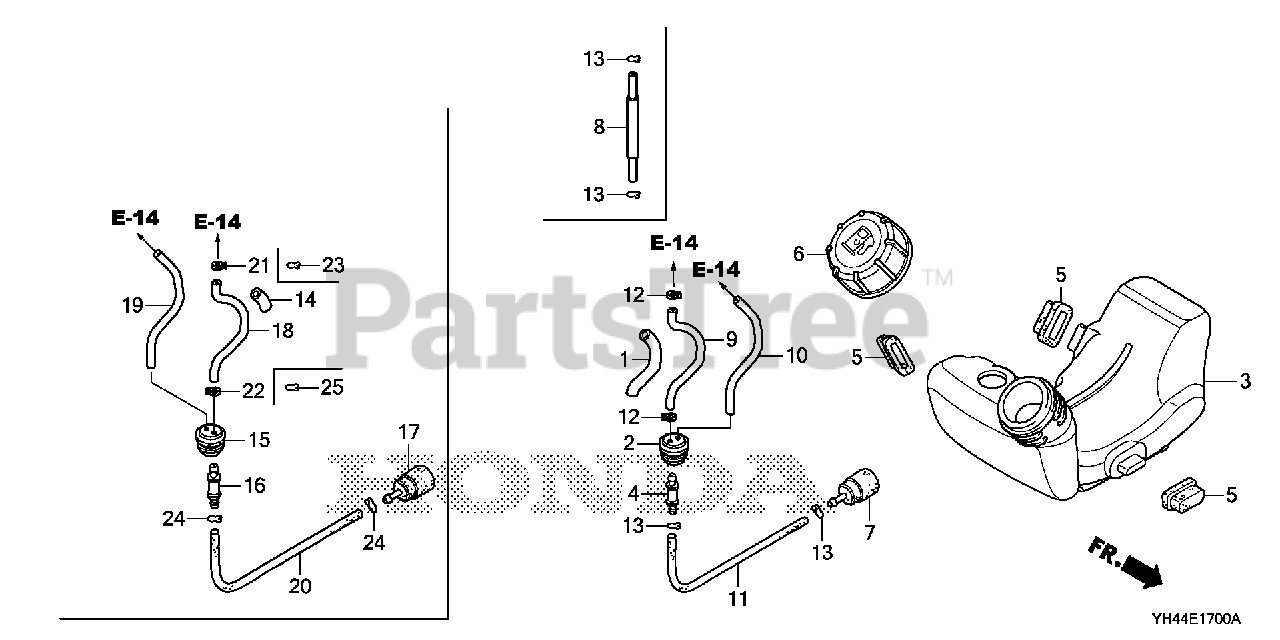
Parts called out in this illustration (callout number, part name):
1	PROTECTOR, TUBE
2	GROMMET, FUEL TUBE
3	TANK, FUEL
5	RUBBER, TANK MOUNTING
6	CAP ASSY., FUEL TANK
7	FILTER, FUEL
9	TUBE, FUEL
10	TUBE, FUEL RETURN
11	TUBE A, FUEL
12	CLAMP, TUBE
13	CLIP, TUBE
14	PROTECTOR, TUBE
15	GROMMET, FUEL TUBE
16	JOINT, FUEL TANK
17	FILTER, FUEL
18	TUBE, FUEL
19	TUBE, FUEL RETURN
20	TUBE A, FUEL
21	CLAMP, TUBE (D5.5)
22	CLAMP, TUBE (D5.5)
24	CLIP, TUBE (B1 5)
